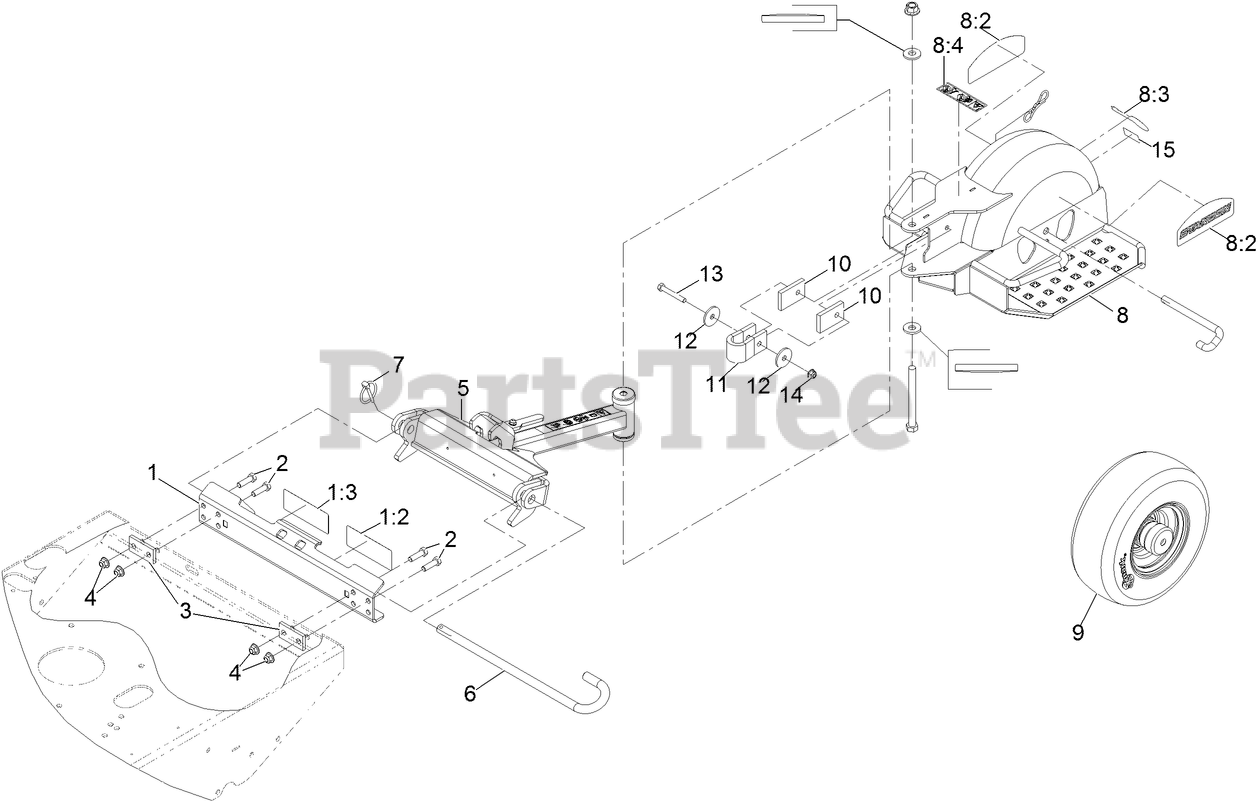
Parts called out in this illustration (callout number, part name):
1	ASM, MOUNT PLATE
1:2	DECAL-BELT DRIVE WARNING
1:3	DECAL-WARNING, SULKY
2	SCREW-HH
3	PLATE,BACK-UP (PLATED)
4	NUT-HF, NI
5	ASM, DRAW BAR
6	PIN, PIVOT
7	PIN-LYNCH
8	ASM-SULKY FRAME W/ DECALS
8:2	DECAL, STANDON
8:3	DECAL, EXMARK
8:4	DECAL-WARNING HAND PINCH
9	ASM, WHEEL AND BEARINGS
10	PAD,STOP
11	STOP, ROTATION
13	SCREW-HH
14	NUT-HF, NI
15	Decal-Patent Ttco.Com
